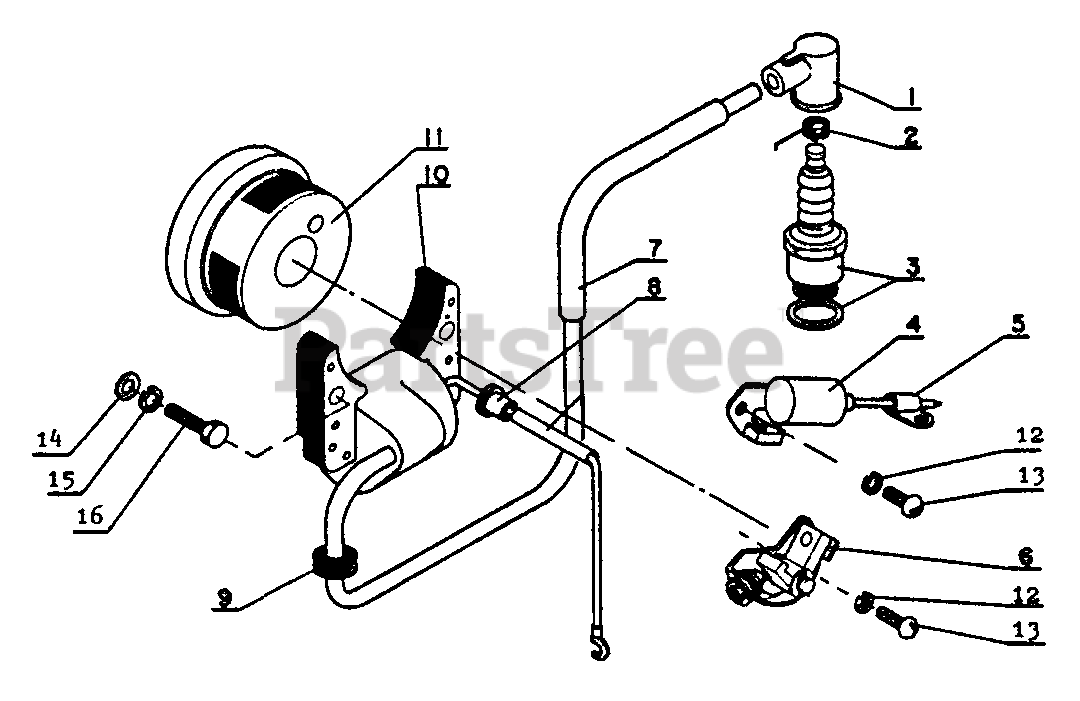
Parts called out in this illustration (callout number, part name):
1	CAP, SPARK PLUG
2	TERMINAL, SPARK PLUG CAP
3	SPARK PLUG
4	CONDENSER
6	CONTACT POINT SET
10	COIL, IGNITION
11	FLYWHEEL
12	LOCKWASHER - 4
13	SCREW - 4X10
14	WASHER - 5
15	LOCKWASHER - 5
16	BOLT - 5X25
